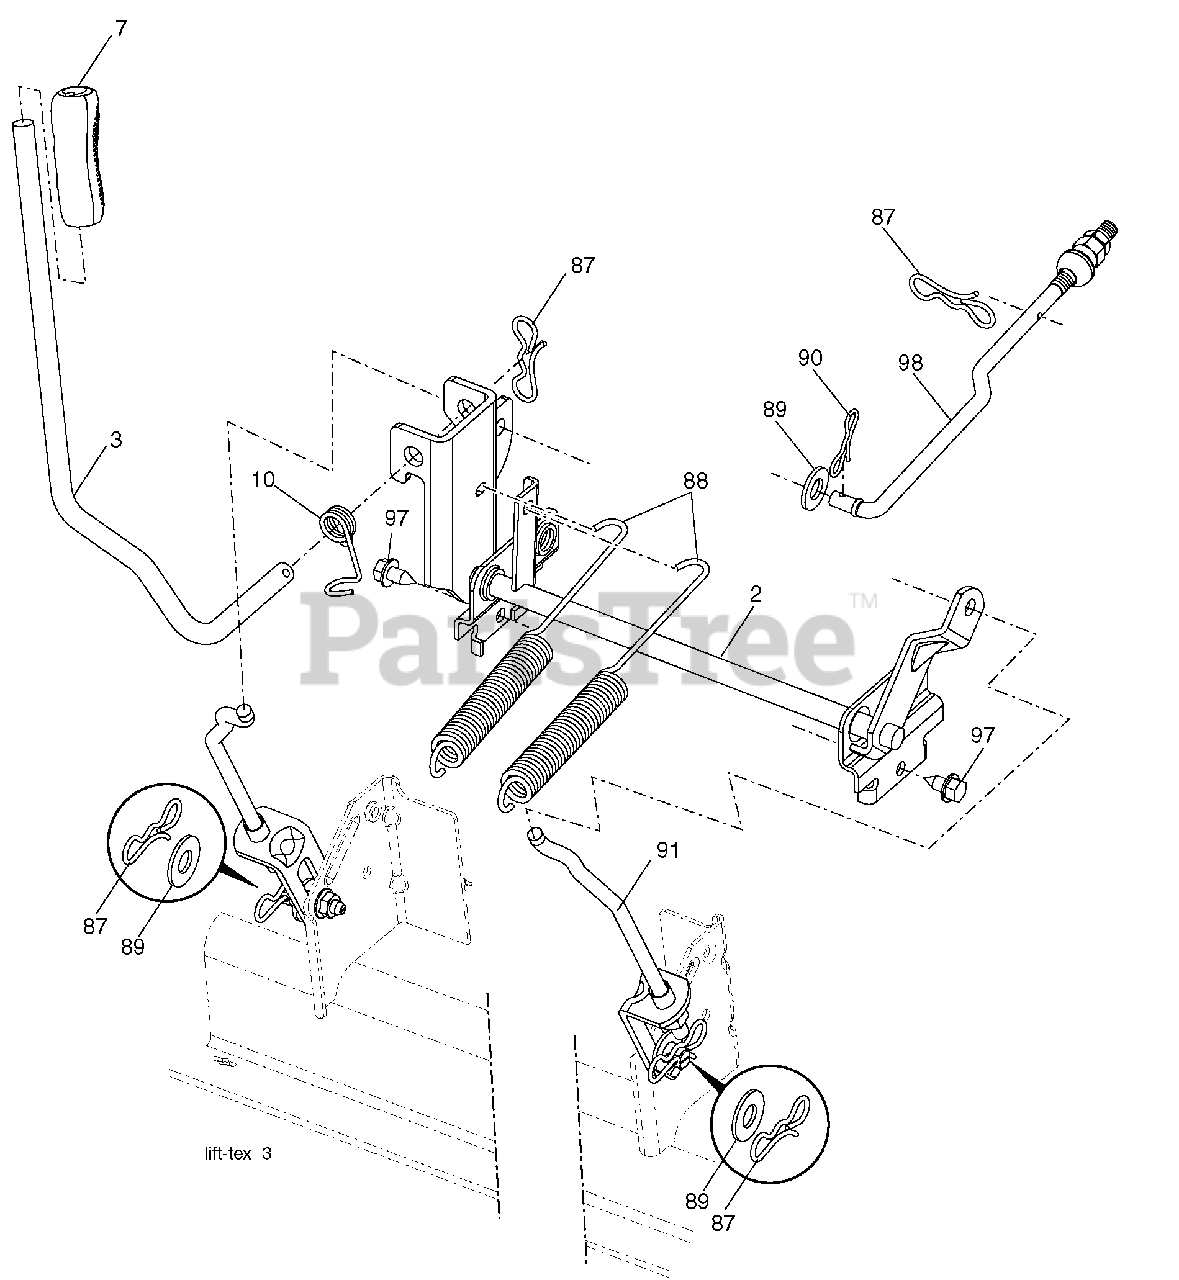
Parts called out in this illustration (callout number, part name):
2	Shaft Asm., Lift
3	Lever Asm., Lift Rh
7	Grip, Lever
10	Spring Torsion
87	Pin Cotter 7/16 Bow Tie Lock
88	Spring Lift Assist
89	Washer Clear Zinc
90	Pin Cotter 5/16 Bow Tie Lock
91	Link Lift Susp Mower Rear
97	Screw 3/8-16 x .75 Smgml Tap/R.Z
98	Link Lift Susp. Front Mower
